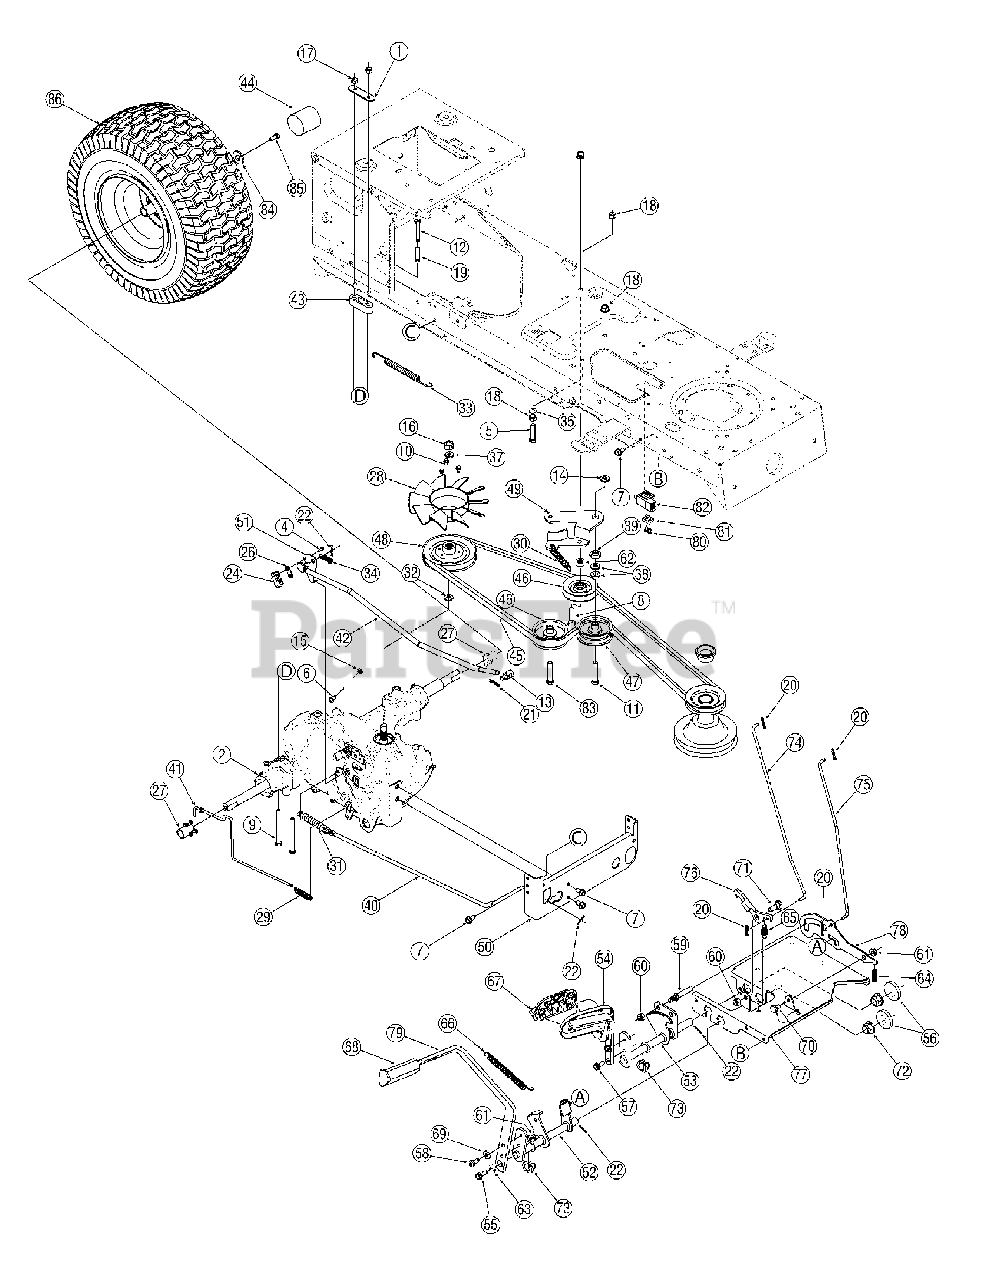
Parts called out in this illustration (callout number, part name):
2	Hydrostatic Transmission
3	Harness Assembly
4	AB Screw #8-18 x 0.375
5	Hex Bolt 3/8-16 x 1.5
6	TT Screw 1/4-20 x 0.5
7	AB Screw 5/16-12 x 0.75
8	TT Sems Screw 3/8-16 x 1.250
9	Hex Bolt 5/16-18 x 3.5
10	Carriage Screw
11	Hex Bolt 3/8-16 x 2.25
12	Screw, 1/4-20 x 1.50
13	Ferrule
14	Flat Washer,.385 x 1.0 x .135
15	Hex Lock Nut 1/4-20
16	Hex Nut, 1/2-20
17	Flange Lock Nut, 5/16-18
18	Flanged Lock Nut 3/8-16
19	Spacer,.260 x.372 x 1.030 Lg
20	Flanged Lock Nut 3/8-16
21	Cotter Pin
22	Cotter Pin
24	Switch
26	Insulator Nut Plate
27	Sleve, 0.765 x 1.5
28	Blade Fan
29	Extension Spring
30	Extension Spring
31	Extension Spring
32	Wire Ring
33	Extension Spring
34	Extension Spring
35	Lock Washer
36	Flat Washer
37	Lock Washer
38	Flat Washer
39	Shoulder Spacer
40	Brake Rod
41	Bypass Rod
42	Control Rod
43	Transaxle Spacer
44	Hub Cap
45	V Belt, A x 78" Lg
46	Idler Pulley
47	Flat Idler Pulley
48	Input Pulley
55	TT Screw 5/16-18 x 0.875
56	Flat Washer,.64 x 1.24 x.06
57	LD Screw 5/16-18 x 0.75
58	TT Screw 5/16-18 x 0.75
60	Flange Lock Nut, 3/8-16
61	Flange Lock Nut, 5/16-18
62	Jam Nut 7/16-20
63	Lock Washer 5/16
64	Compression Spring
65	Extension Spring
66	Extension Spring
67	Control Pedal
68	Brake Control Pedal
69	Flat Washer
70	Shoulder Screw
71	Shoulder Screw
72	Hex Flange Bearing
73	Hex Flange Bearing
74	Brake Lock Control Rod
75	Cruise Control Rod
76	Cruise Latch
78	Hydro Lockout Bracket
81	Switch Plate
82	Interlock Switch
83	Screw, 3/8-16 x 1.50
84	Bell Washer,.340 x.872 x.060
85	Screw, 5/16-24 x.750
87	Pin, Cotter
